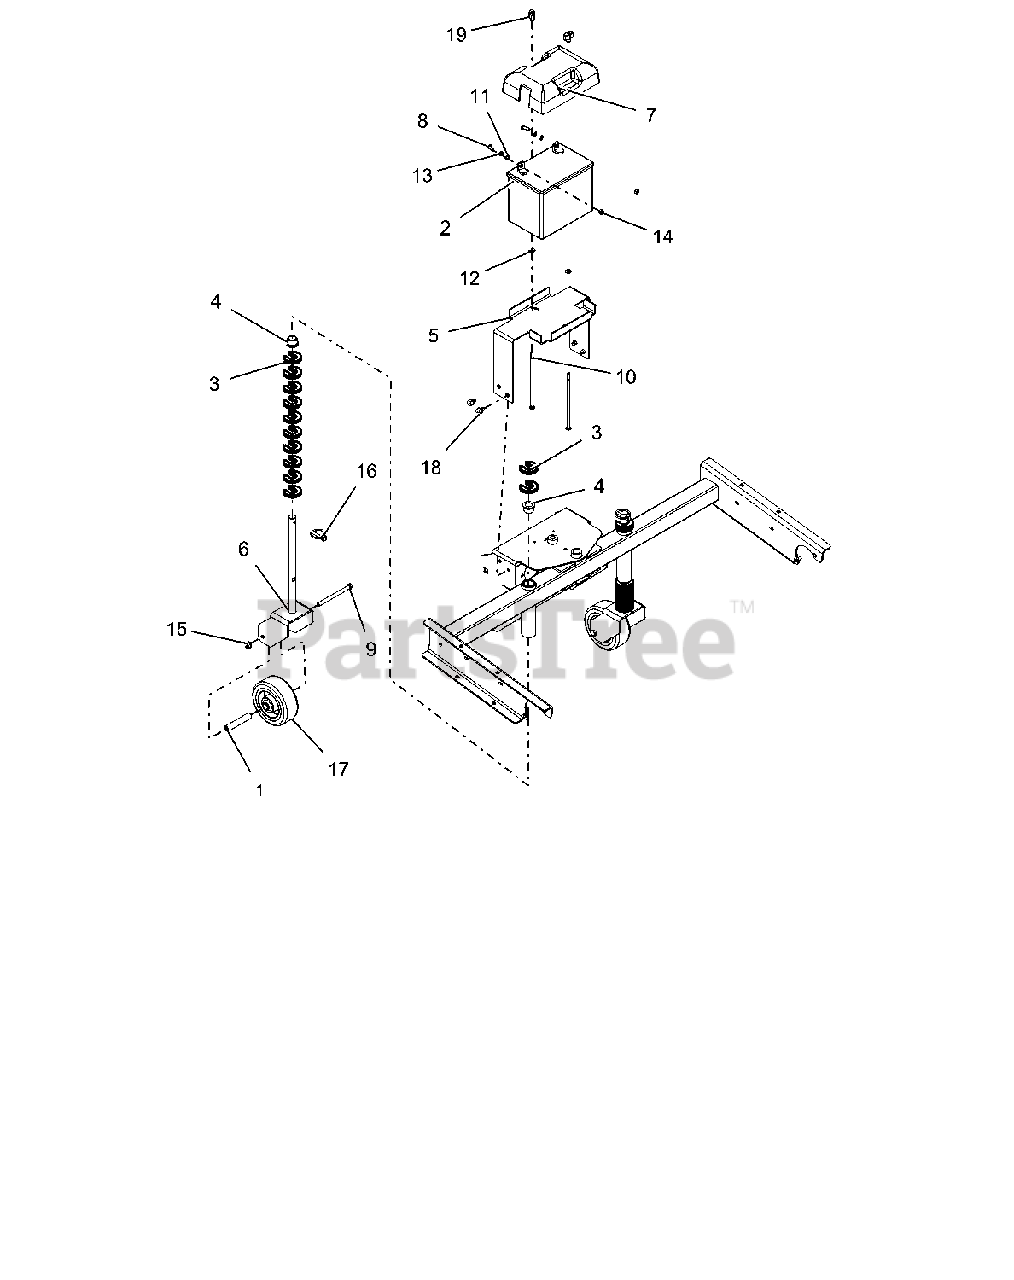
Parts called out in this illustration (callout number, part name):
1	SPACER, CASTER WHEEL
2	BATTERY, 300 CCA 10U1L
3	CLIP-HOC FIXED
4	BUSHING, FLANGE .75X.75X1.0
5	TRAY, BATTERY - POWER BRUSH
6	FORK, CASTER
7	COVER, BATTERY
8	@BLT-HEX .25-20X.75 GR5 YWZC
9	@BLT-HEX .38-16X4.50 GR5 YWZC
10	@BLT-RDHDSQNK .25-20X7.00 G2YZ
11	@WSHR-LK .25X.062 REG YWZC
12	@WSHR-FL-STL.281X.62X.065 YWZC
13	WSHR-FL-STL .265X.50X.087YWZC
14	@NUT-HEX .25-20 YWZC
15	@NUT-LK-TOP-FLG .38-16 YWZC
16	PIN, 1/4X1-9/16 LYNCH
17	WHEEL, CASTER - 5"OD
18	@SCR-TAP .38-16X.50 HWH TR YWZ
19	KNOB, WING - .25-20 UNC
